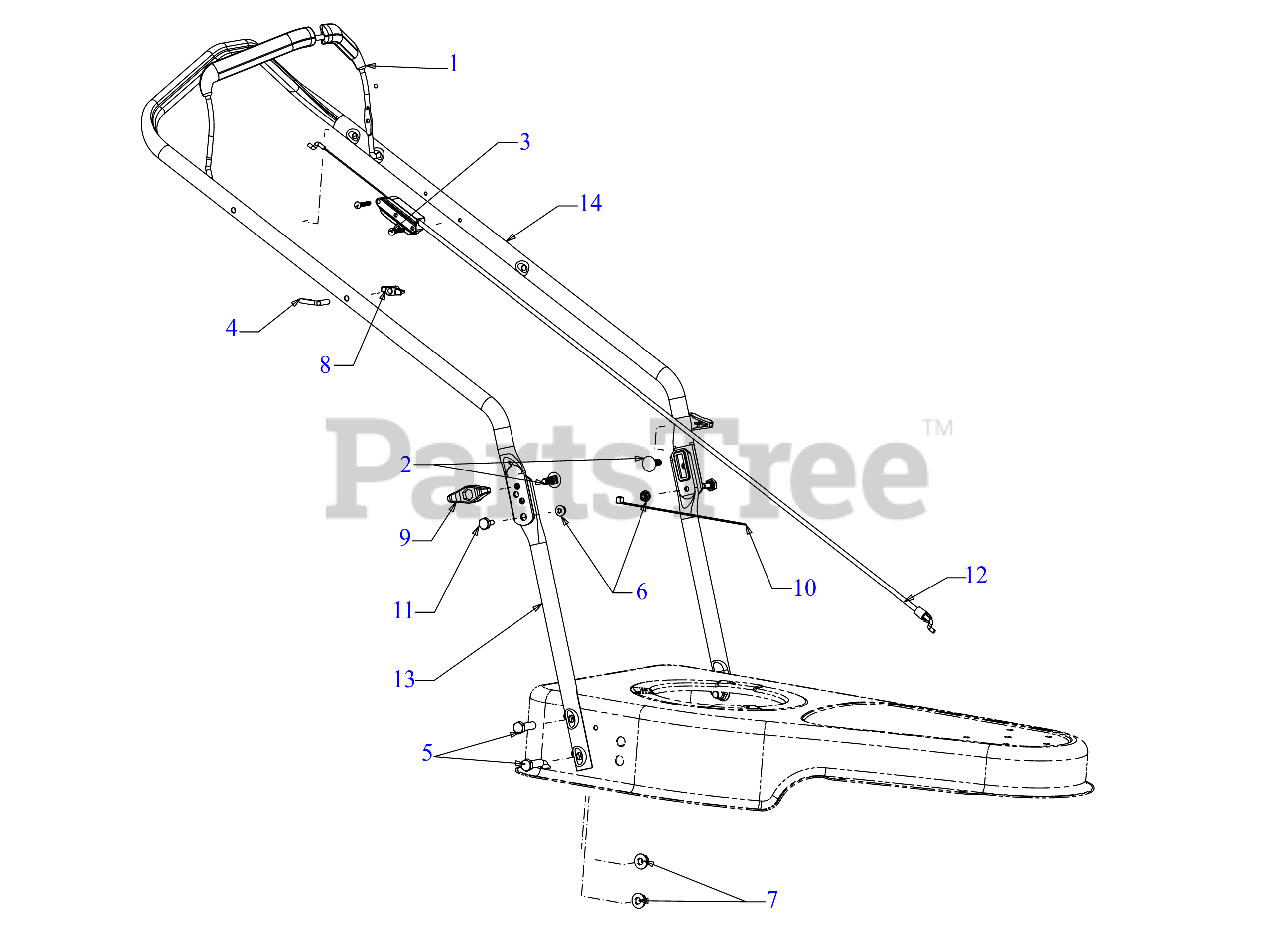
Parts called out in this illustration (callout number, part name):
1	OPERATOR BAIL ASSEMBLY
2	SCREW 5/16-18 x 1.00 GR5
3	SCREW-PANPHIL TAP 10-16 x 1.25
4	EYEBOLT 1/4-20
5	SCREW 3/8-16 x 1.25 GR5
6	FLANGE LOCK NUT
8	HANDLE KNOB
9	WING KNOB 5/16-18
10	7" CABLE TIE
11	SHOULDER SCREW
12	ERS CONTROL CABLE 46.7"
14	UPPER HANDLE ERGO
